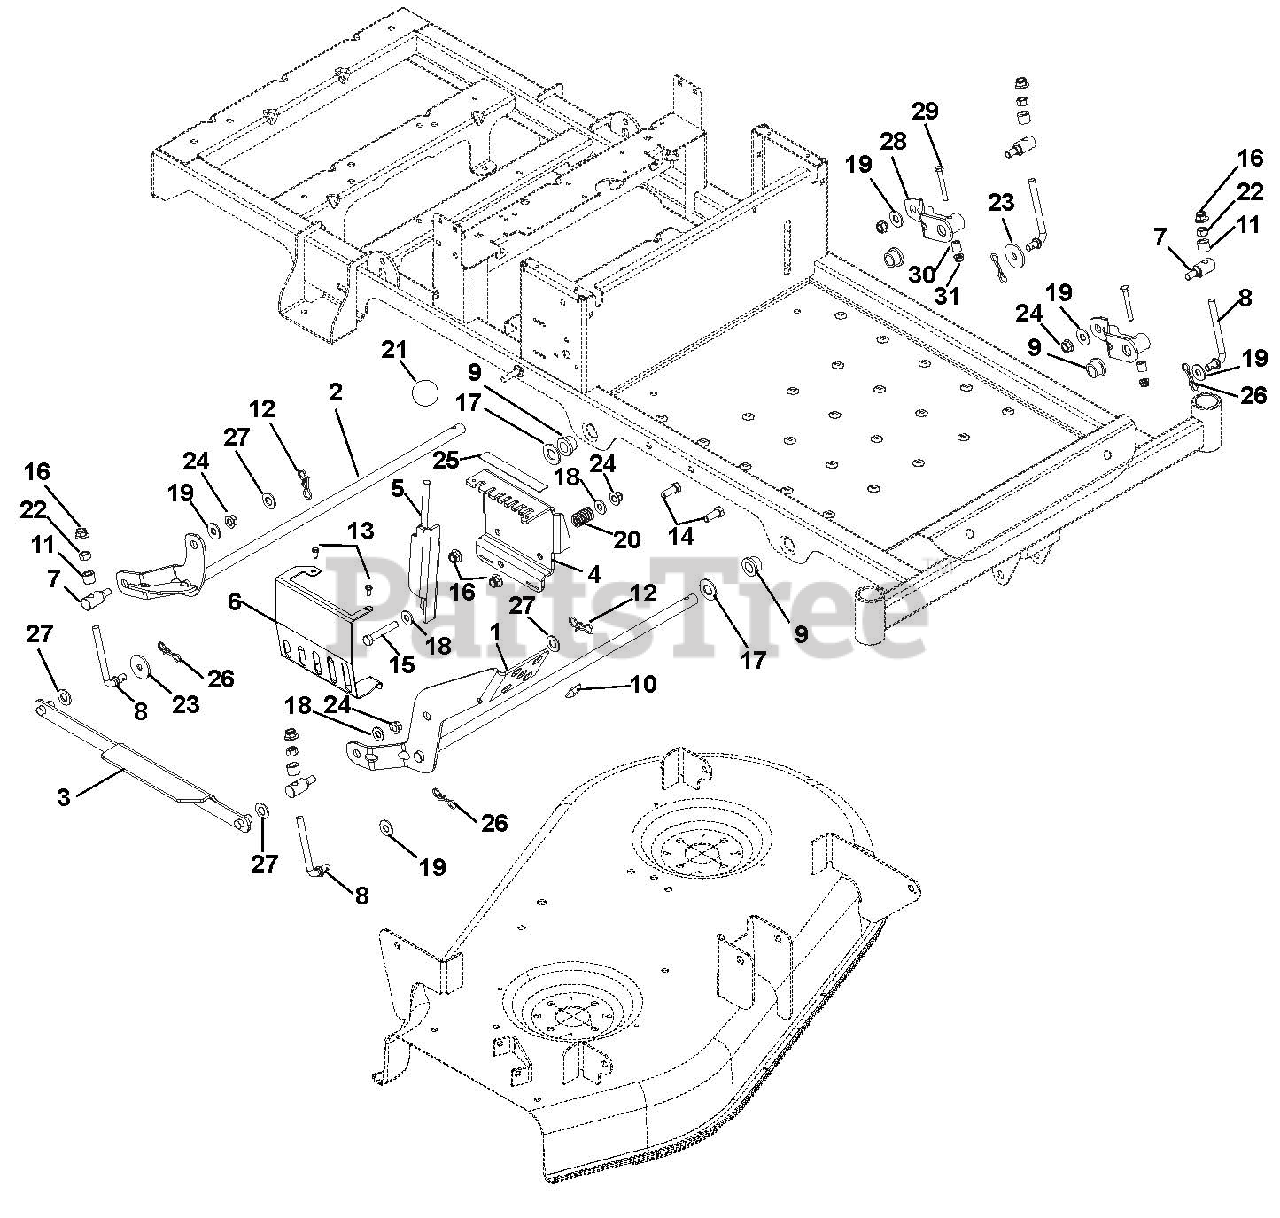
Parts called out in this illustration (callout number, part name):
1	WLDMT, FOOTPEDAL
2	WLDMT, REAR DECK LIFT
3	WMT, LIFT/HOC LINK
4	BRKT, HOC
5	WMT, HOC LEVER
6	GUARD, DECK HOC
7	TRUNNION, DECK ADJUSTER
8	WIREFORM, DECK ADJUSTMENT
9	BSHG-FLG .629X.879X.469X1.250
11	BSHG-SLV .391X.688X.52 PM
13	SCR,TAP #10-24X.50 HWH TR ZCC
14	BLT,HEX .38-16X1.00 G5 ZCC
15	BLT,HEX .38-16X2.25 G5 ZCC
16	NUT,NYL-FLG .38-16 GF ZCC
17	WSHR, FLT .656X1.313X.095 ZCC
18	WSHR,FLT .375X.875X.083 ZCC
19	WSHR,FLT .406X.812X.065 ZCC
20	SPRG, COMPRESSION
21	KNOB,BALL -BLACK 1.47" .375-16
22	NUT-STD .375-16 G2 ZCC
23	WSHR, FLT .380X1.50X.125 ZCC
24	NUT-LK-TOP-FLG .38-16 ZC120
25	DECAL, HEIGHT OF CUT
26	PIN, BOWTIE .091X1.875 ZCC
27	WSHR-FL-NYL .518X1.000X.080
28	WLDMT, DECK LIFT ARM
29	BLT, HEX .25-20X2.00 G5 ZCC
30	BSHG-SLV .265X.500X.500
31	NUT,NYL-FLG .25-20 GF ZCC
